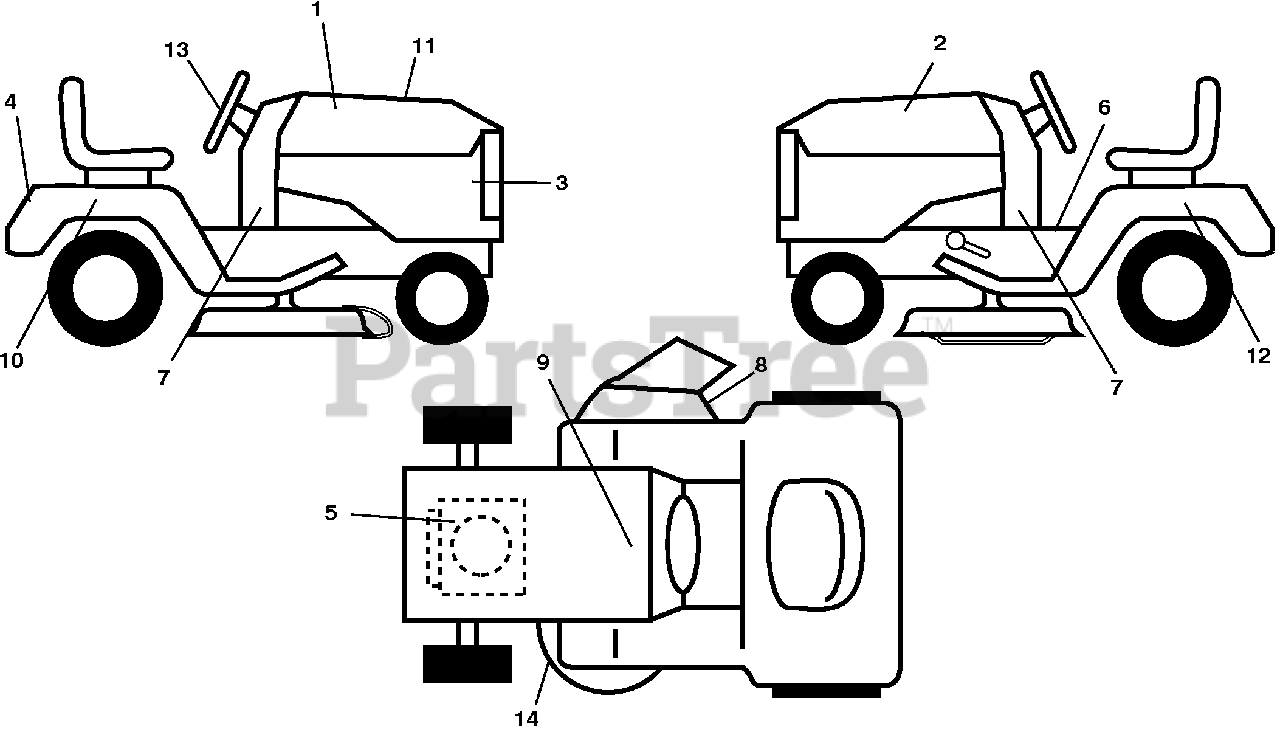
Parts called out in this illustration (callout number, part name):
1	Decal, Hood RH
2	Decal, Hood LH
3	Decal, Side Panel
4	Decal, Fender
5	Decal, Eng H.P.
6	Decal, Fender Operator's
7	Decal, Lower Dash
8	Decal, Warning
9	Decal, Battery Dnge/Poi
10	Decal, Fender SD RH
11	Decal, Replacement
12	Decal, Fender SD LH
13	Decal, Steering Wheel
14	Decal, Mower Schematic
14	Pad, Footrest Control
14	Decal, Bypass
14	Pad, Footrest, LH
14	Manual, Operator's (Eng/French)
14	Manual, Parts (Eng/French)
